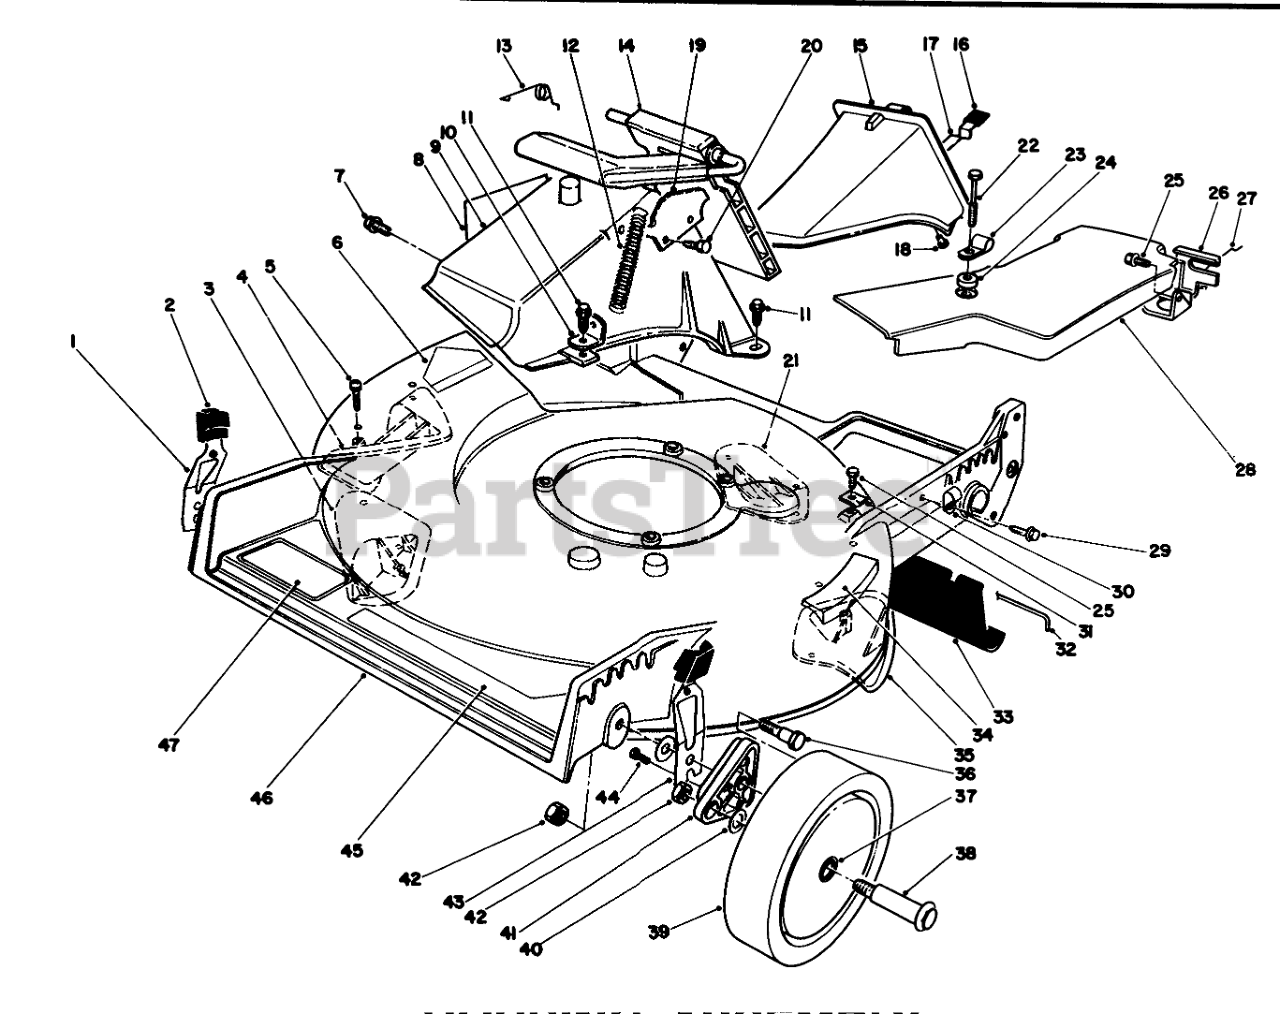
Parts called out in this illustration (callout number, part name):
1	RH SPRING ARM ASSEMBLY
2	KNOB-ARM
3	KICKER
4	KICKER
5	SCREW-PPH
6	DECAL-DANGER
7	SCREW AND WASHER ASM
8	DECAL - DANGER
9	TUNNEL-DISCHARGE
10	Bracket-Spring
11	SCREW-HWH
12	SPRING-DOOR
13	RETAINER-DOOR
14	DOOR ASSEMBLY
15	Discharge Plug Assembly (Incl. Ref. #16-18)
16	GRIP-LATCH
17	LATCH-PLUG, DISCHARGE
18	RIVET-HEAD, FLAT
19	DOOR LATCH PLATE
20	SCREW-PLASTITE
21	KICKER
22	SCREW-SPECIAL
23	CLAMP-CABLE
24	WASHER
25	SCREW-HWHTF
26	Bracket-Adj. Trac
27	RETAINER-CABLE
28	BELT COVER
29	SCREW-HWH
30	CLAMP-CABLE
31	CLAMP-CABLE
32	ROD-SHIELD
33	SHIELD-TRAILING
34	DECAL - STEP PAD INT'L
35	KICKER
36	SCREW-SHOULDER
37	BUSHING
38	WHEEL BOLT
39	Wheel & Tire Assembly (Incl Ref. #37)
40	WASHER
41	ARM-PIVOT, FRONT
42	Nut
43	LH SPRING ARM ASSEMBLY
44	SCREW-HWH
45	DECAL - DECK
46	Housing Assembly (Incl. Ref. #3-6, 21, 35, 5 on pg. 3, & 30-31 on pg. 4)
47	DECAL
